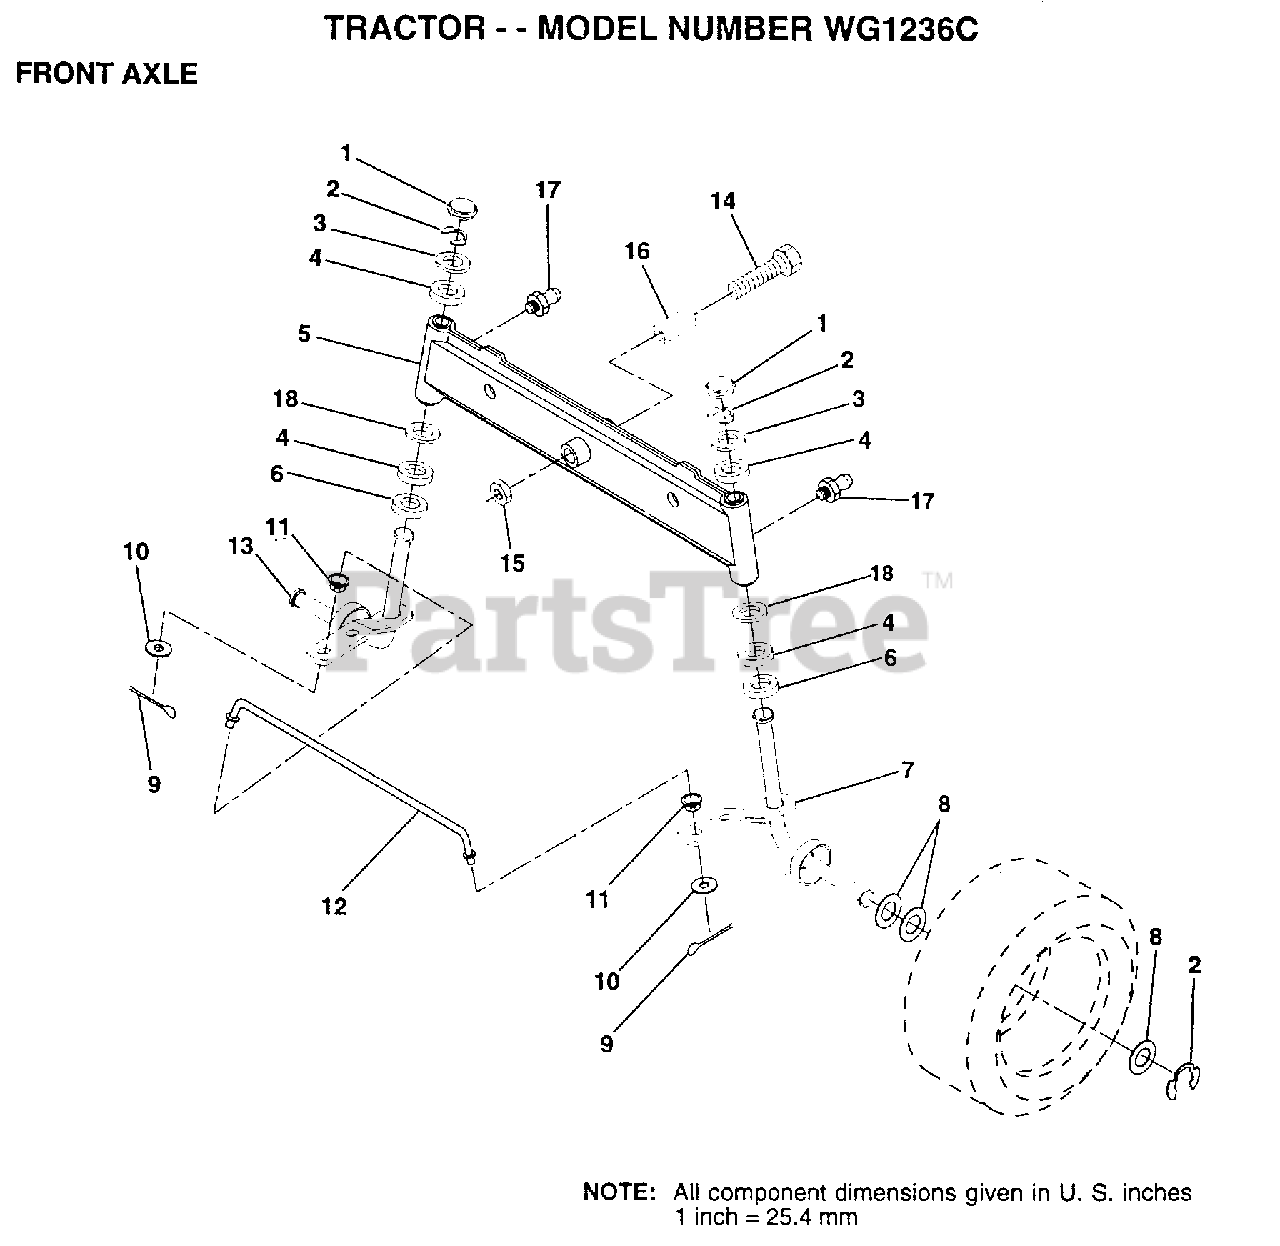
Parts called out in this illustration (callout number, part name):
1	CAP
2	RING
3	WASHER
4	COL. SRTG. BEAR.
5	AXLE ASM FRONT
6	WASHER .T
7	SPINDLE ASM RH
8	WASHER
9	COTTER PIN
10	WASHER
11	BUSHING.DRAGLINK
12	TIE ROD
13	SPINDLE ASM LH
14	BOLT HEX 5/8-11
15	"NUT-LOC,FLANGE LT"
16	BEARING
17	ZERK M
18	WASHER
